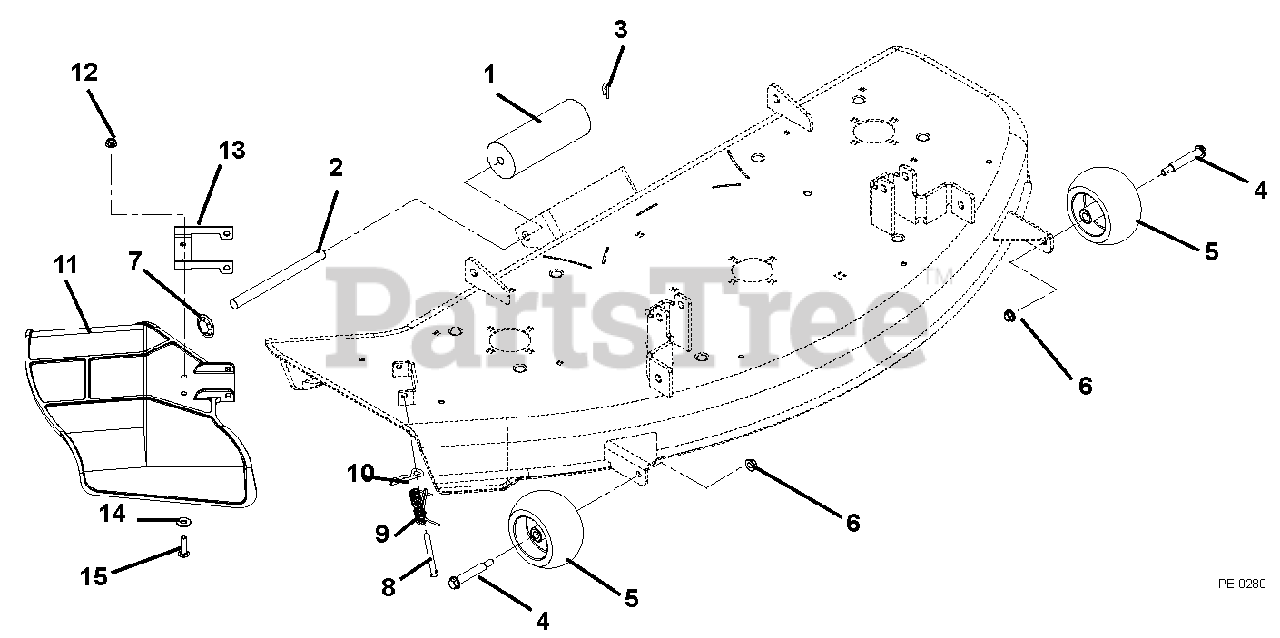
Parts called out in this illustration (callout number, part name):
1	Roller (404)
2	Pin, Roller (404)
3	Pin, Spring Clip (404)
4	Bolt, Shoulder .38-16 x 2.50 Hex Washer Head Grade 5
5	Wheel 5 x 3
6	Nut, Locking-Top-Flange .38-16
7	Push Nut, .625 Shaft (404)
8	Clevis Pin
9	Spring, Torsion
10	Pin, Hair .08 x .18 x 1.18
11	Plastic Chute
12	Nut, Locking, Top Flange .31-18
13	Chute Reinforcement
14	Washer, Flat Steel .38 x .875 x .083
15	Screw, Socket Head, Button Head .31-18 x .75
